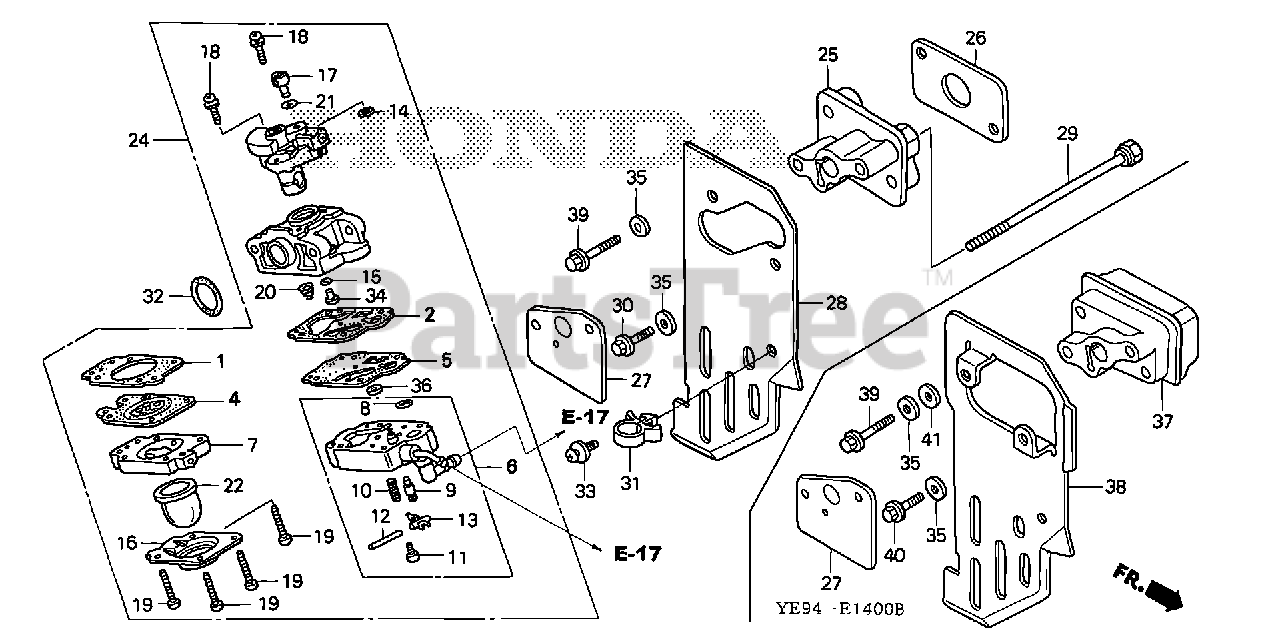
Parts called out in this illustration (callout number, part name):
1	GASKET, METERING DIAPHRAGM
2	GASKET, PUMP (CARBURETOR NO.)
4	DIAPHRAGM ASSY., METERING
5	DIAPHRAGM, PUMP
6	BODY ASSY., PUMP (CARBURETOR NO.)
7	BODY ASSY., AIR PURGE
8	SCREEN, INLET (CARBURETOR NO.)
9	VALVE, INLET NEEDLE
10	SPRING, METERING LEVER
11	SCREW, METERING LEVER PIN
12	PIN, METERING LEVER
13	LEVER, METERING
14	RING, SPRING RETAINING
16	COVER, PRIMER PUMP
18	SCREW, THROTTLE COLLAR
19	SCREW, PUMP COVER
20	SPRING, PUMP
22	PUMP, PRIMER
24	CARBURETOR ASSY. (WYL 127A)
26	GASKET, INSULATOR
27	GASKET, CARBURETOR
29	BOLT, HEX. (5X75)
31	CLIP, WIRE HARNESS
32	O-RING (14.8X2.4)
33	SCREW-WASHER (5X10)
34	JET (#33.5) (CARBURETOR NO.)
34	JET (#35.5) (CARBURETOR NO.)
34	JET (#34.5) (CARBURETOR NO.)
35	GASKET, PROTECTOR
36	FILTER, FUEL INLET (CARBURETOR NO.)
37	INSULATOR, CARBURETOR
38	GUIDE, AIR INLET
39	BOLT, FLANGE (5X35)
40	BOLT, FLANGE (5X32)
41	WASHER, PLAIN (5MM)
